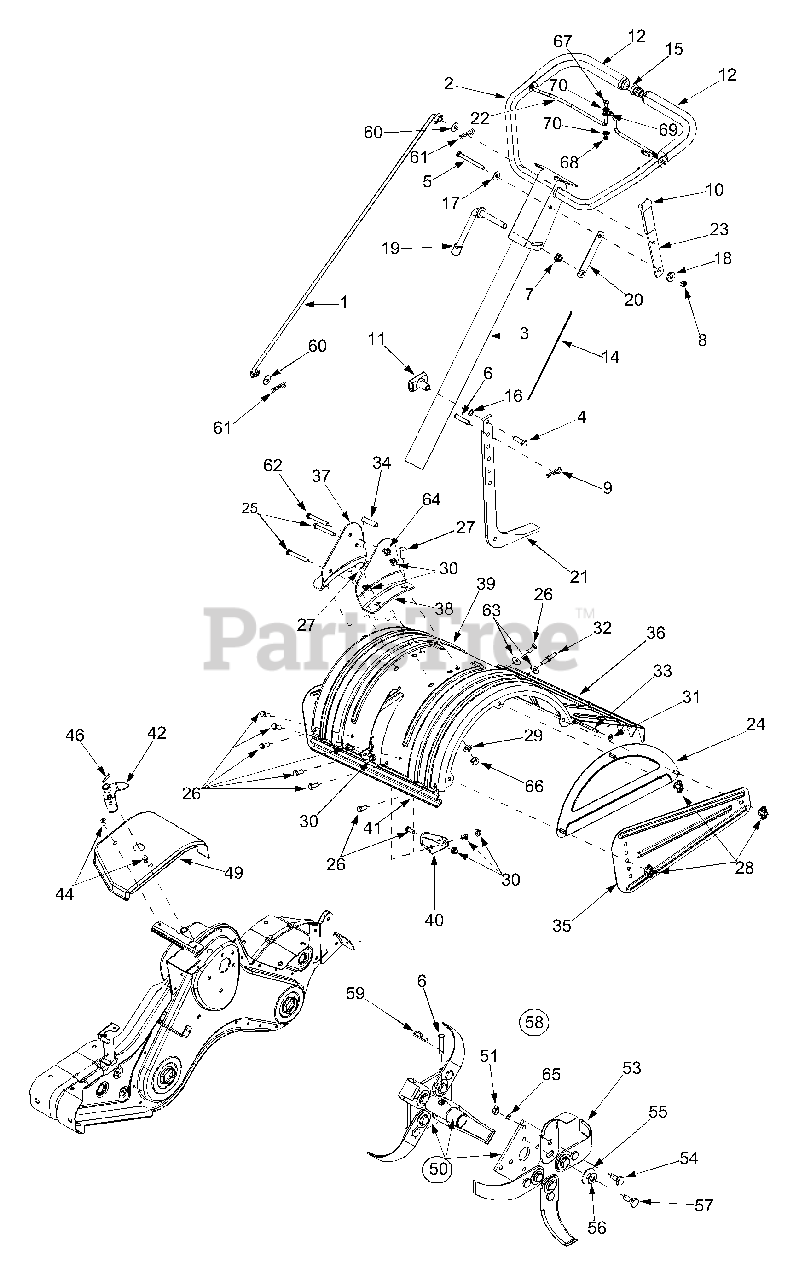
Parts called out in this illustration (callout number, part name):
1	Shift Rod
4	Hex Screw 3/8-16 x 1.25
5	Hex Screw 5/16-18 x 3.25
6	Clevis Pin 3/8-1.62
7	Flange Lock Nut 3/8-24
8	Hex Lock Nut 5/16-18
9	Cotter Pin
11	T-Knob
12	Foam Grip
14	Cable Tie
15	End Plug
16	Flat Washer 3/8 ID x.620 OD
17	Bell Washer.340 ID x.872 OD
18	Shoulder Spacer
19	Handle Adjustment Crank
20	Hex Nut Retainer Bracket
25	Hex Cap Screw 5/16-18 x 2.75
26	Hex Cap Screw 5/16-18 x.750
27	Carriage Bolt 3/8-16 x 1.0
28	Wing Nut
29	Lock Washer 3/8
30	Flange Nut 5/16-18
31	Cap Nut
32	Hex Screw 5/16-18 x.75"
34	Spacer.322 x.625 x 2.0
42	Shift Crank Ass'y
44	Screw 1/4-14 x.625
46	Spiral Pin 3/16 x 1.0
51	Hex Nut 3/8-24
54	Shoulder Bolt
55	Flat Washer .51" ID x 1.50" OD
56	Bell Washer .515" ID x 1.14" OD
57	Shoulder Bolt
59	Internal Cotter Pin
60	Rubber Washer
61	Cotter Pin
62	Hex Screw 3/8-16 x 2.75"
63	Flat Washer
64	Flange Nut.344 ID x.62 OD
65	Lock Washer
66	Hex Nut 3/8-16
67	Truss Screw 1/4-20 x.65
68	Hex Lock Nut 1/4-20
69	Battery Hose Clamp 5/16
70	Flat Washer.260 ID x.720 OD
